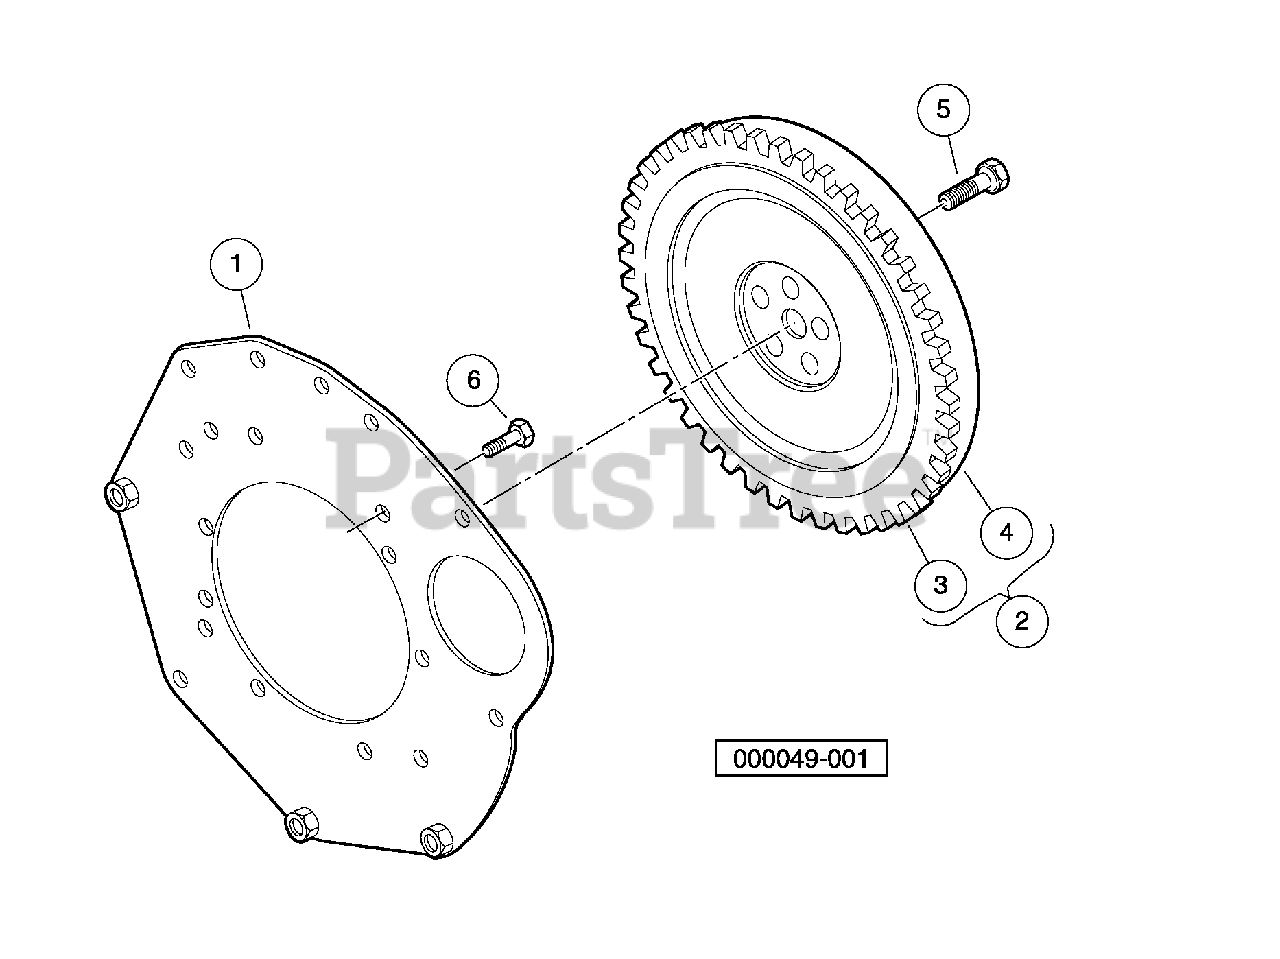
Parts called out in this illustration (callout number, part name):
1	Plate, Rear End
2	Flywheel
3	Gear, Ring, D722
4	Flywheel
5	Bolt, Flange Head, M10 X 1.5 X 25
6	Bolt, End Plate
